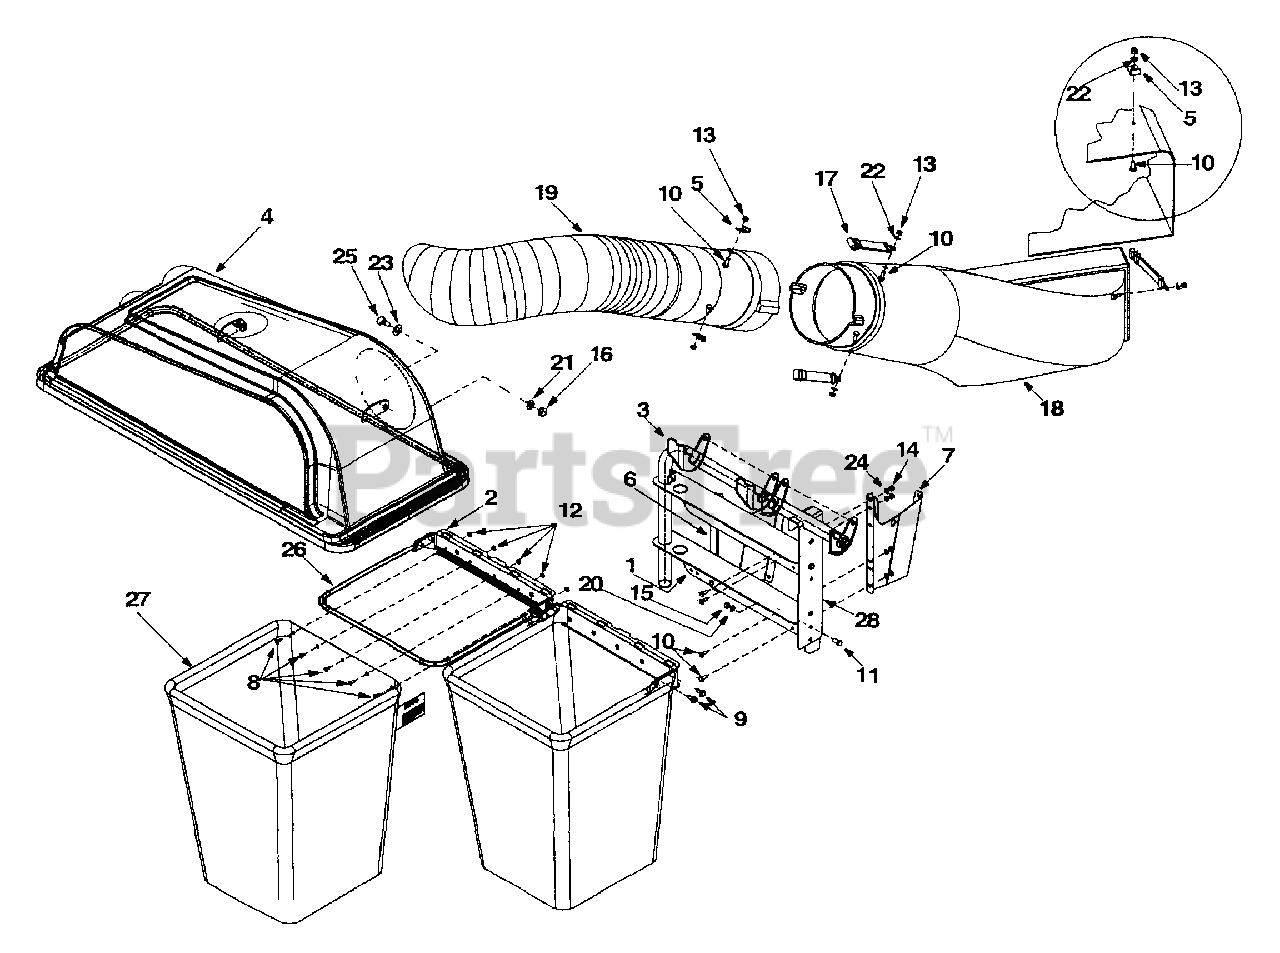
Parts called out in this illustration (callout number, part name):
4	Cover Assembly
5	Retainer Hook Bracket
8	Mach. Screw: #10-24 X 0.5"
9	Screw, TT- 5/16-18 X 0 625"
10	Hex Bolt 1 /4-20 X 0.620" Gr 5
11	Hex Bolt: 5/16-18 X 0.75" Gr. 5
12	Hex Sems Nut 10-24
13	Hex Lock Nut
14	Hex Nut: Gr 5
15	Hex Nut 5/16-18
16	Hex Nut: 3/8-16 Gr 8
17	Retainer Strap Assembly
18	Discharge Chute
19	Chute Tube
20	Lock Washer: 5/16
21	Lock Washer
22	Spring Washer
23	Bell Washer
24	Lock Washer: 1/4
25	Shoulder Screw
27	Catcher Bag
